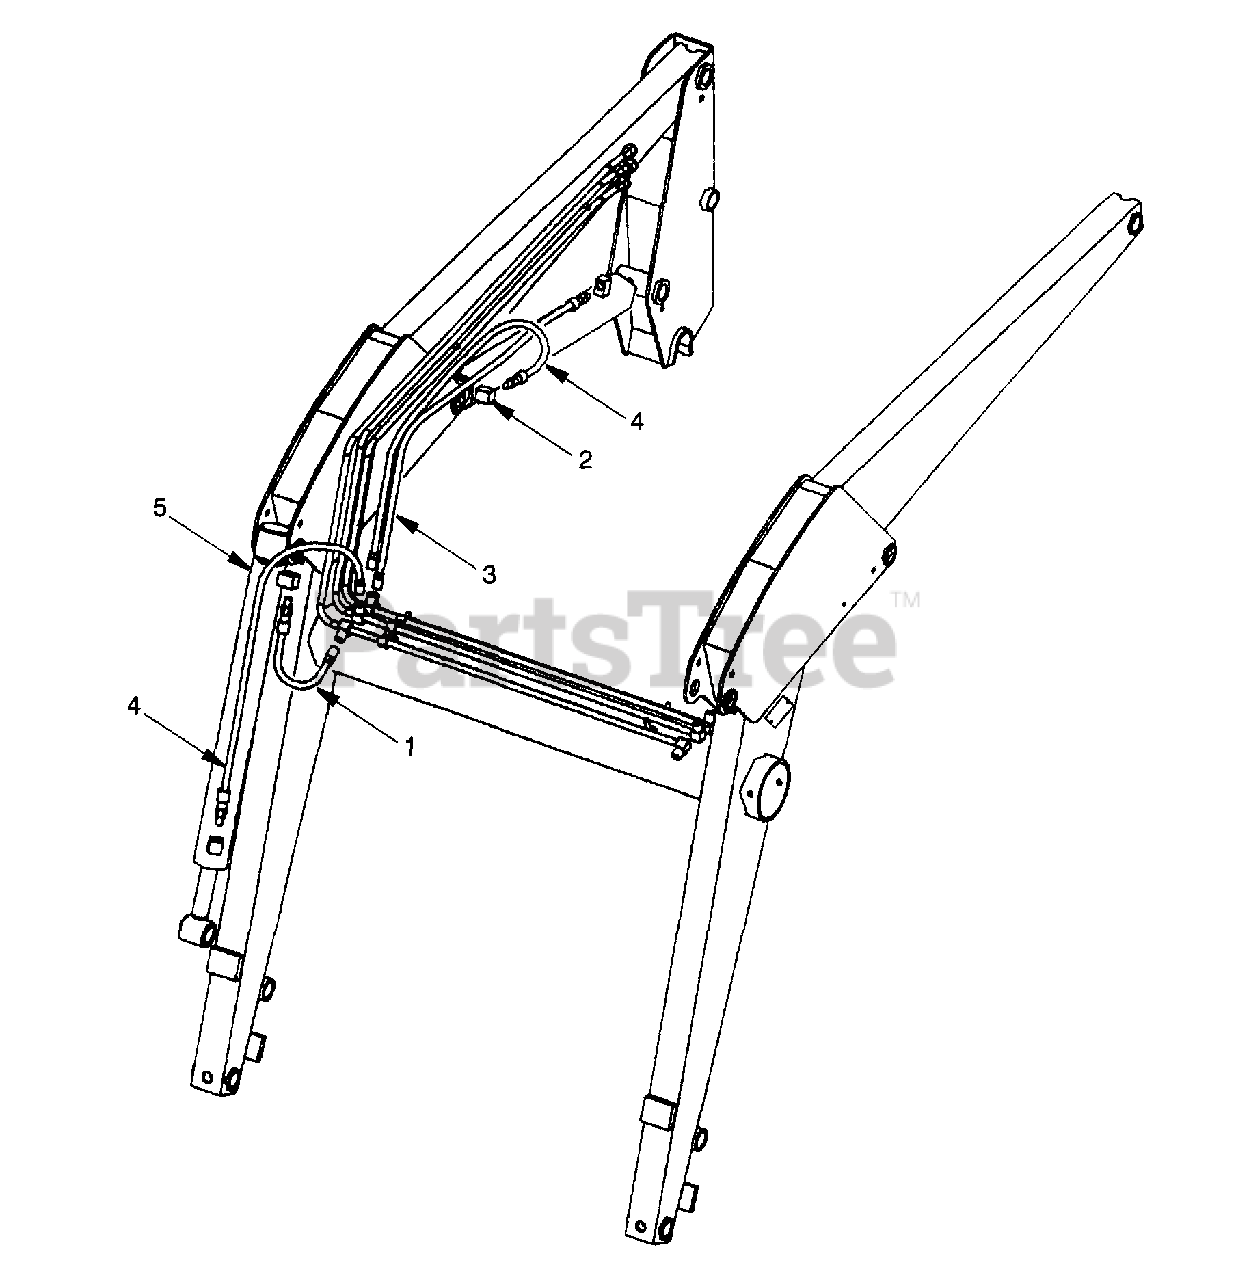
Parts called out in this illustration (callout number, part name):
1	Hose, 3/8-23", 9/16 SAE M x 3/4 JICM
2	Boom Cylinder
3	Hose, 3/8-50", 9/16 SAE M x 3/4 JICM
4	Hose, 3/8-27", 9/16 SAE M x 3/4 JICM
5	Bucket Cylinder
